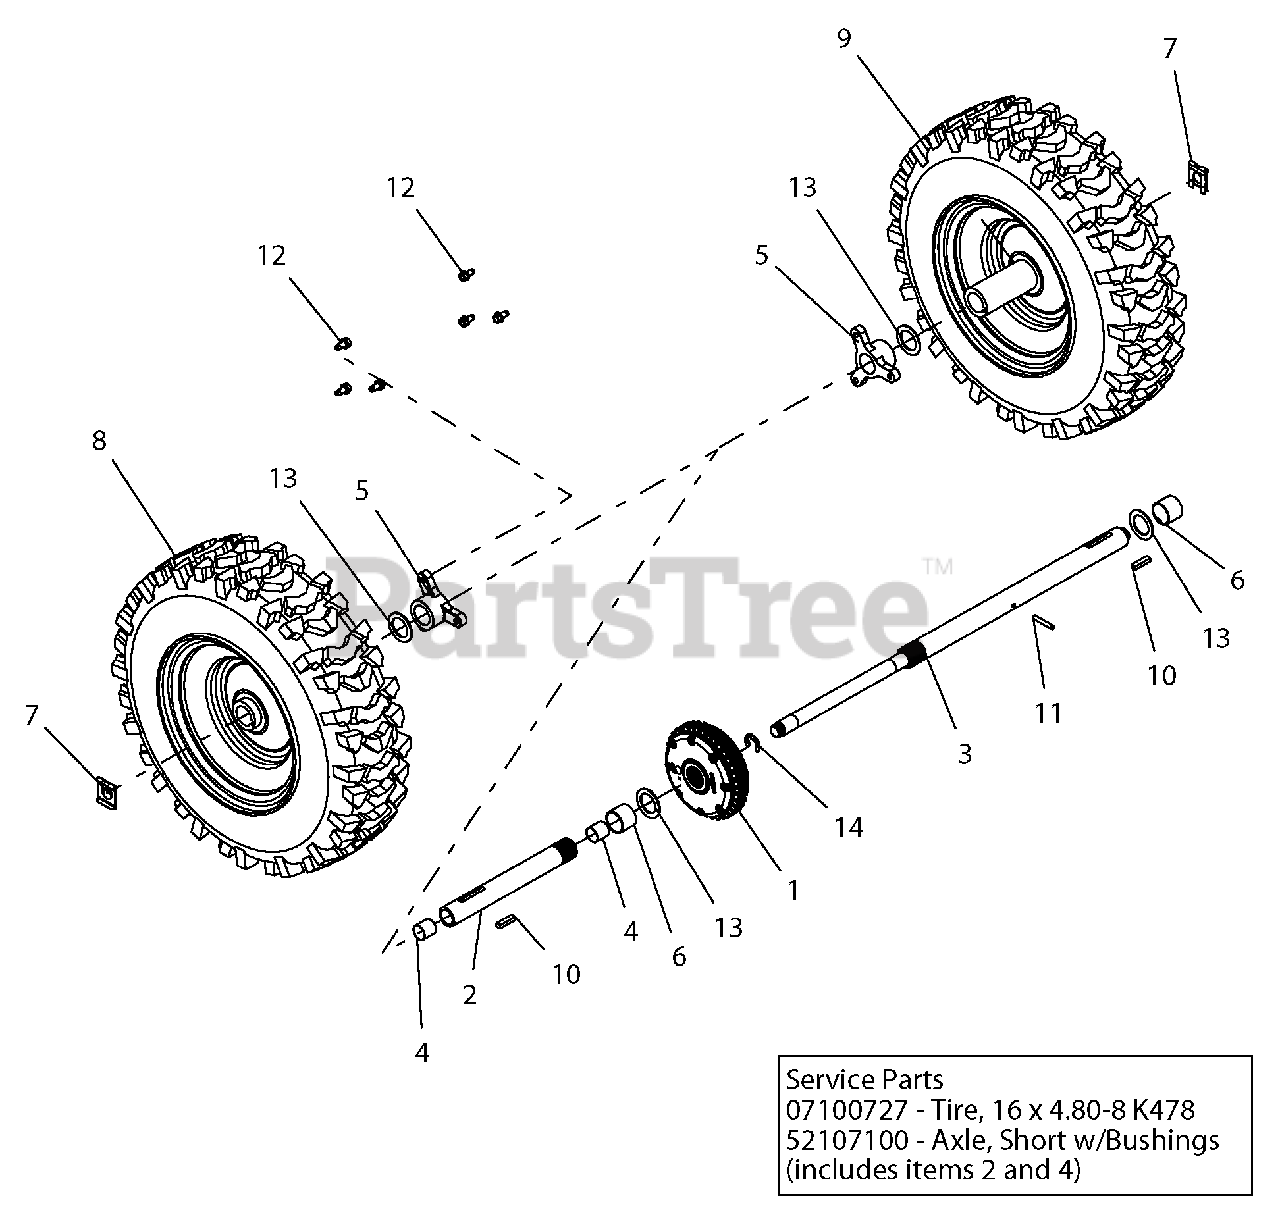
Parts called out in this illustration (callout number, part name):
1	DIFFERENTIAL, AUTOMATIC
2	KIT, SHORT AXLE W/BUSHINGS
3	AXLE, LONG - DIFFERENTIAL
4	BSHG-SLV .706X.764X.75 BRZ
5	BUSHING, AXLE
6	BSHG-SLV, 1.012X1.125X.875
7	CLIP, SNAP .625 DIA
8	TIRE/WHEEL,RH 16X4.8-8 DIFF T2
9	TIRE/WHEEL,LH 16X4.8-8 DIFF T2
10	KEY-RECT .25X.188X1.00
11	PIN-ROLL .188X1.25
12	SCR-TAP .25-20X.50 HWH TR YWZ
13	WSHR-FL-STL 1.010X1.505X.062YZ
14	RG-RTNG-EXT .625X.042
